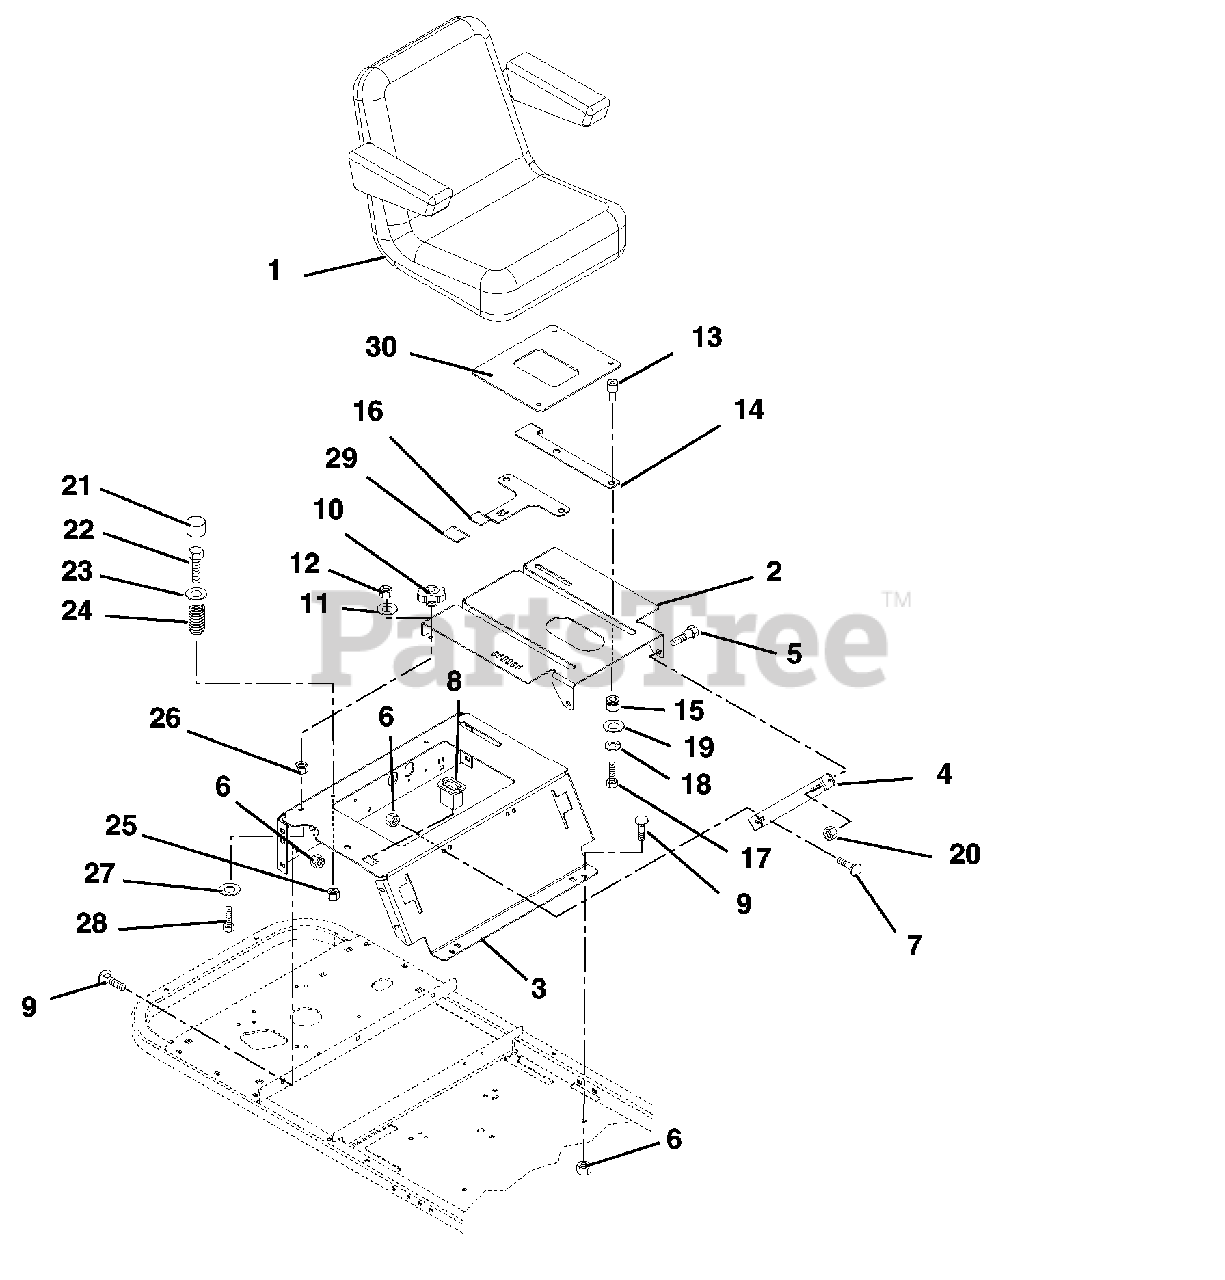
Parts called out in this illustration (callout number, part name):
1	SEAT, HIGH BACK 2805 SERIES
2	SEAT PLATE
3	SEAT BOX
4	BRACKET, SEAT PLATE
5	BOLT-SHLDR .375-16X.150
6	@NUT-LK-NYL-FLG .38-16 YWZC
7	@BLT-RDHDSQNK .38-16X1.00 G5YZ
8	HOURMETER-QUARTZ 80VDCMAX
9	@BLT-RDHDSQNK .38-16X1.00 G5YZ
10	KNOB-CLAMPING, .312-18 NYLOC
11	WSHR-FL-STL .328X1.0X.094 YWZC
12	@NUT-LK-NYL .312-18 YWZC
13	SPACER, SEAT TOP
14	SEAT STOP
15	SPACER, SEAT BOTTOM
16	LEVER, SEAT ADJUSTMENT
17	@BLT-HEX .31-18X2.25 GR5 YWZC
18	@WSHR-LK .31X.078 REG YWZC
19	@WSHR-FL-STL.312X.734X.065 YWZ
20	@NUT-LK-TOP-FLG .38-16 YWZC
21	HUB CAP
22	@BLT-HEX .31-18X1.00 GR5 YWZC
23	WSHR-FL-STL .328X1.0X.094 YWZC
24	SG. COMP 2.9L X 2.02OD 200LB
25	@NUT-LK-NYL-FLG .31-18 YWZC
26	@NUT-SPNLK-FLG .312-18 YWZC
27	WSHR-FL-STL .505X1.00X.062YWZC
28	@BLT-RDHDSQNK .31-18X3.50 G5YZ
30	SEAT SUPPORT PLATE
